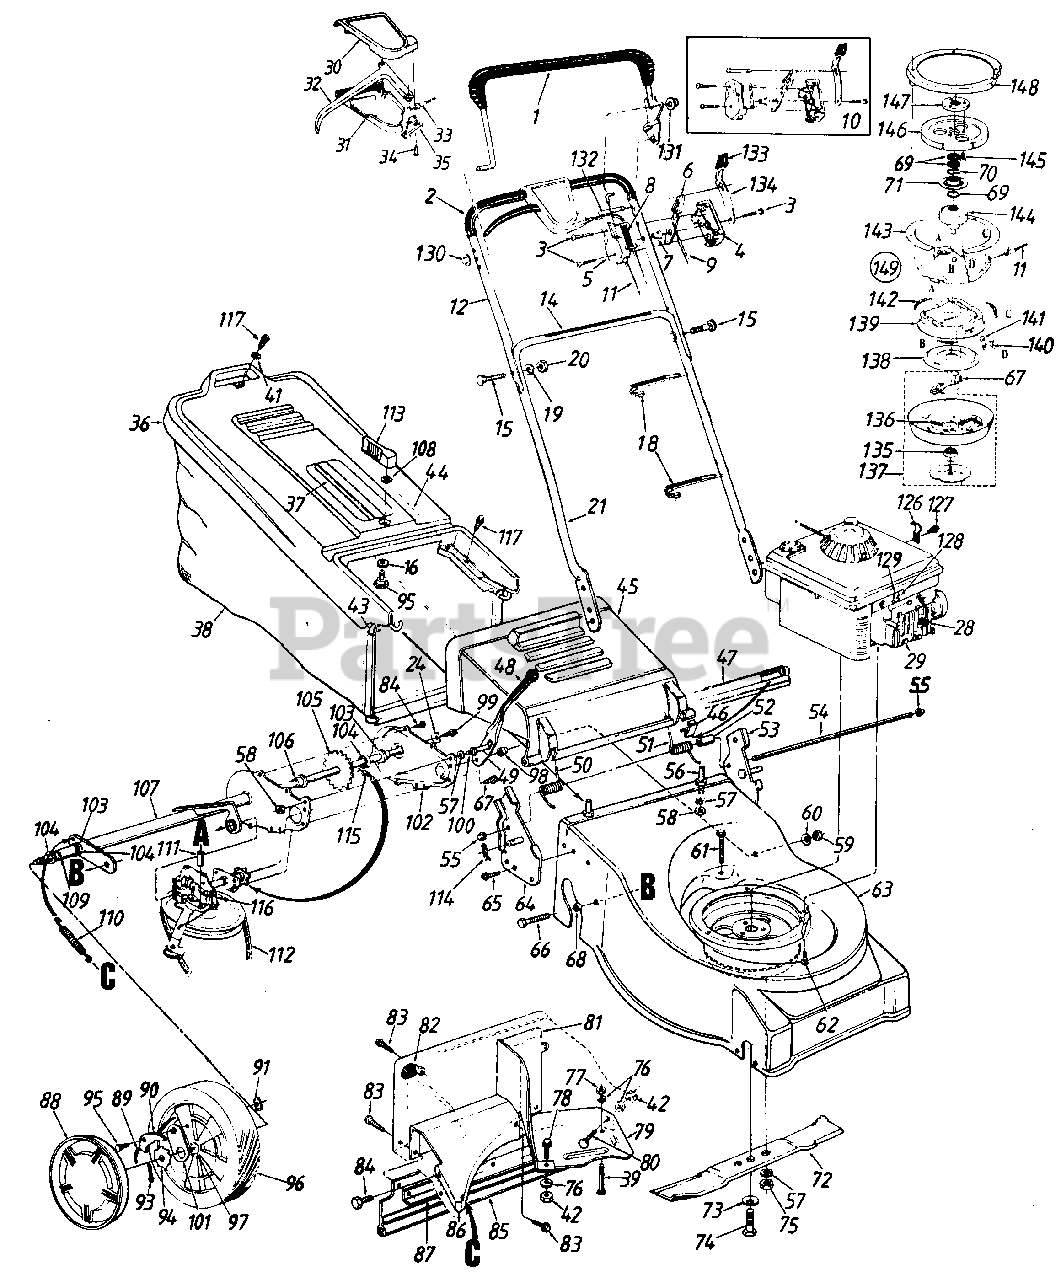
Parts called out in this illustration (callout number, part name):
1	Control Handle Ass'y.
2	Grip
3	Truss Mach. B-Tap Scr. #12 x 1.5" Lg.
4	Control Panel Half
5	Clutch Panel Half
6	Throttle Control Lever
7	Control Disc Pin
8	Control Label-Throttle
9	Throttle Wire-58" Lg.
10	Control Housing Comp.
11	Control Cable-52" Lg.
12	Upper Handle (Painted)
14	Instruction Label-Handle
15	Curved Carriage Bolt 5/16-18 x 1.38" Lg.
16	Bowed Washer
18	Cable Tie
19	L-Wash. 5116" I.D.
20	Hex Nut 5/16-18 Thd.
24	Bell-Wash. .265" I.D. x .75"
28	Spark Plug Boot
29	Engine
30	Control Cover Half-Upper
31	Control Cover Half-Lower
32	Control Lever
33	Drive Cable-53" Lg.
34	Flat C-Sunk Hd. Tap Scr. #10 x .75" Lg.
35	Cable Mtg. Cap
36	Hardtop Bag Cover
37	Hardtop Handle
38	Grass Bag
39	Truss Mach. Scr. 1/4-20 x 1.0" Lg.
41	Fl-Wash. .281" I.D. x .62"
42	Hex Nut 1/4-20 Thd.*
43	Front Catcher Frame
46	Deflector Plug
47	Seal-Extrusion
49	Spring Lever
50	Torsion Spring-R.H.
51	Torsion Spring-L.H.
52	Spacer.255" I.D.
53	Handle Brkt. Ass'y.-L.H.
54	Hinge Pin 17.75" Lg.
55	Cap Speed Nut
56	Shld. Pin 3/8-24 x 1.43" Lg.
57	L-Wash. 3/8" I.D.
58	Hex Jam Nut 3/8-24 Thd.
59	Hex L-Nut 3/8-24 Thd.
60	Bell-Wash. .38" I.D. x .88"
61	Hex Wash. Hd. Tap Scr. 1/4-20 X 1.5" Lg.
62	Hex L-Wash. Hd. Scr. 3/8-16 x 1.5" Lg.
63	483 21" Deck Ass'y.
64	Handle Brkt. Ass'y.-R.H.
65	Hex L-Wash. Hd. AB-Tap Scr. 1/4 x .62" Lg.
66	Hex Wash. Hd. Tap Scr. 3/8-16 x .75" Lg.
67	Hex Wash. Hd. Tap Scr. 1/4-20 x .5" Lg.
68	Spacer.383" I.D.
69	Serrated Washer 1.0" I.D.
70	Wave Washer 1.005" I.D.
71	Serrated Pulley Half
72	21" Blade
73	Bell-Wash. .46" I.D. x .88"
74	Hex Bolt 7/16-20 x 2.0" Lg. (Gr. 5)
75	Hex Nut 3/8-24 Thd. (Gr. 8)
76	L-Wash. 1/4" I.D.
77	Hex Jam Nut 1/4-20 Thd.
78	Hex Bolt 1/4-20 x .85" Lg.
79	Rear Belt Baffle
80	Carr. Bolt 1/4-20 x .50" Lg.
83	Torx Mach. AB-Tap Scr. 1/4 x .62" Lg.
84	Hex B-Tap Scr. 1/4 x .38" Lg.
85	Rear Flap
86	Rear Chute Baffle
87	Retaining Strip
88	Hub Cap
89	Plastic Spring
90	Pawl.345" I.D.
91	Weld Nut 1/4-20 Thd.
93	Cotter Pin 1/8" Dia.
94	Ratchet Wheel 1.62" O.D.
95	Shld. Bolt .342" Dia. x .268
96	Wheel Ass'y. Comp.-Rear
97	Sleeve Bearing 1/2" I.D.
98	Shld. Spacer .50" Dia.
99	Hex Bolt 1/4-20 x .62" Lg. (Gr. 5)
100	Shld. Pin 3/8-24 x 1.43" Lg.
101	Pawl Plate
104	Fl-Wash. .531" I.D. x .93"
105	Rear Axle Ass'y.
106	Hex Flange Bearing
109	Spacer.513" I.D.
110	Extension Spring 3.8" Lg.
111	Spacer.325" I.D.
112	V-Belt
113	Grass Catcher Locking Knob
114	Internal Cotter Pin 5/16" Dia.
115	#48 Chain .50" Pitch x 30 Links
116	Transmission Comp.
117	Hex L-Wash. Hd. AB-Tap Scr. 1/4 X .62" Lg.
126	Cable Clamp
127	Hex B-Tap Scr. #10 x .38" Lg.
128	Hex B-Tap Scr. #10 x .62" Lg.
129	Cable Clamp
130	Push Cap
131	Push Cap
132	Lock Pin .314 Dia. x 1.75"
133	Spring Lever Knob
134	Lockout Spring
135	Ball Brg. .669" I.D. x 1.574"
136	CoLmp. Spring .35 O.D. x 2.0
137	Clutch Blade Housing Ass'y.
138	Clutch Cone
139	Brake Cup Cone
140	Ball Block
141	Steel Ball .50" Dia.
142	Ext. Spring 1.75" Lg.
143	Clutch Housing
144	Fixed Pulley Adapter
145	Flat Hd. Tap Scr. 1/4-20 x .625" Lg.
146	Flywheel
147	Flywheel Adapter
148	Engine Mounting Plate Cover
149	Blade Brake Clutch Ass'y. Comp.
